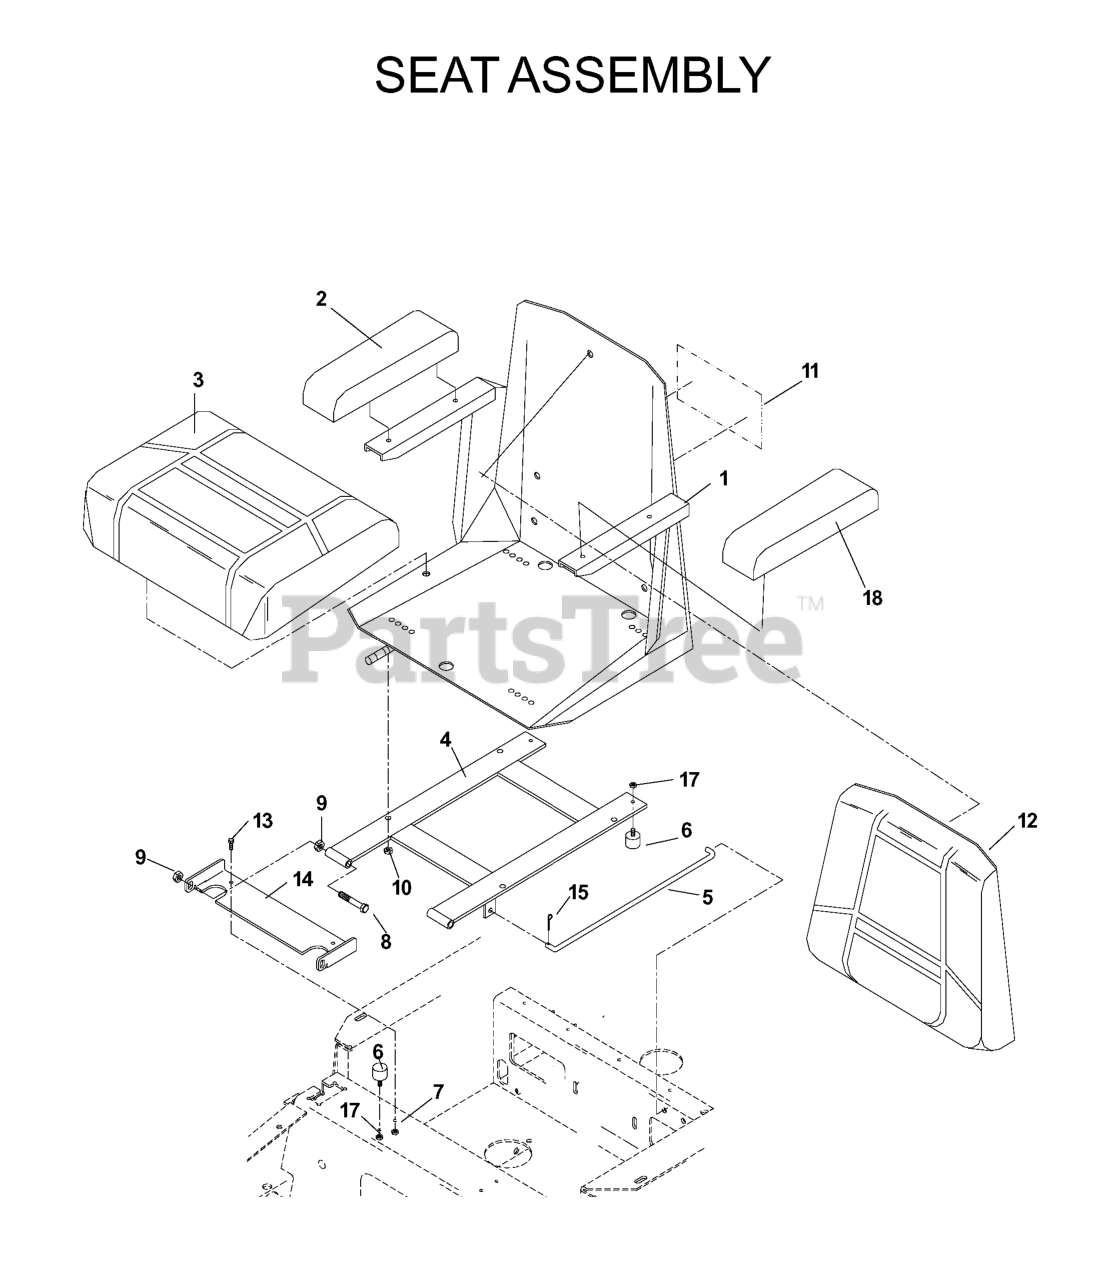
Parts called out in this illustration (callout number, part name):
1	SEAT COMPLETE
2	ARMREST KIT, RH
3	SEAT CUSHION KIT
4	SEAT MOUNT
6	STUD/PLATE MOUNT
7	NUT 1/4C CENTERLOCK
8	HCS 3/8C X 3
9	NUT 3/8C CENTERBLOCK
10	NUT 5/16 NYLOC
11	DECAL, CROWN H
12	BACK CUSHION KIT
13	HCS 1/4C X 3/4 HCS
14	SEAT BRKT W/DECAL
15	RP_COTTER PIN 1/8 X 3/4
16	SLIDE KIT, SEAT ADJ
17	NUT.1/4-20.HEX.NYLOC.ZD
18	ARMREST KIT, LH
539108745	SWITCH-SNAP MOUNT KIT
